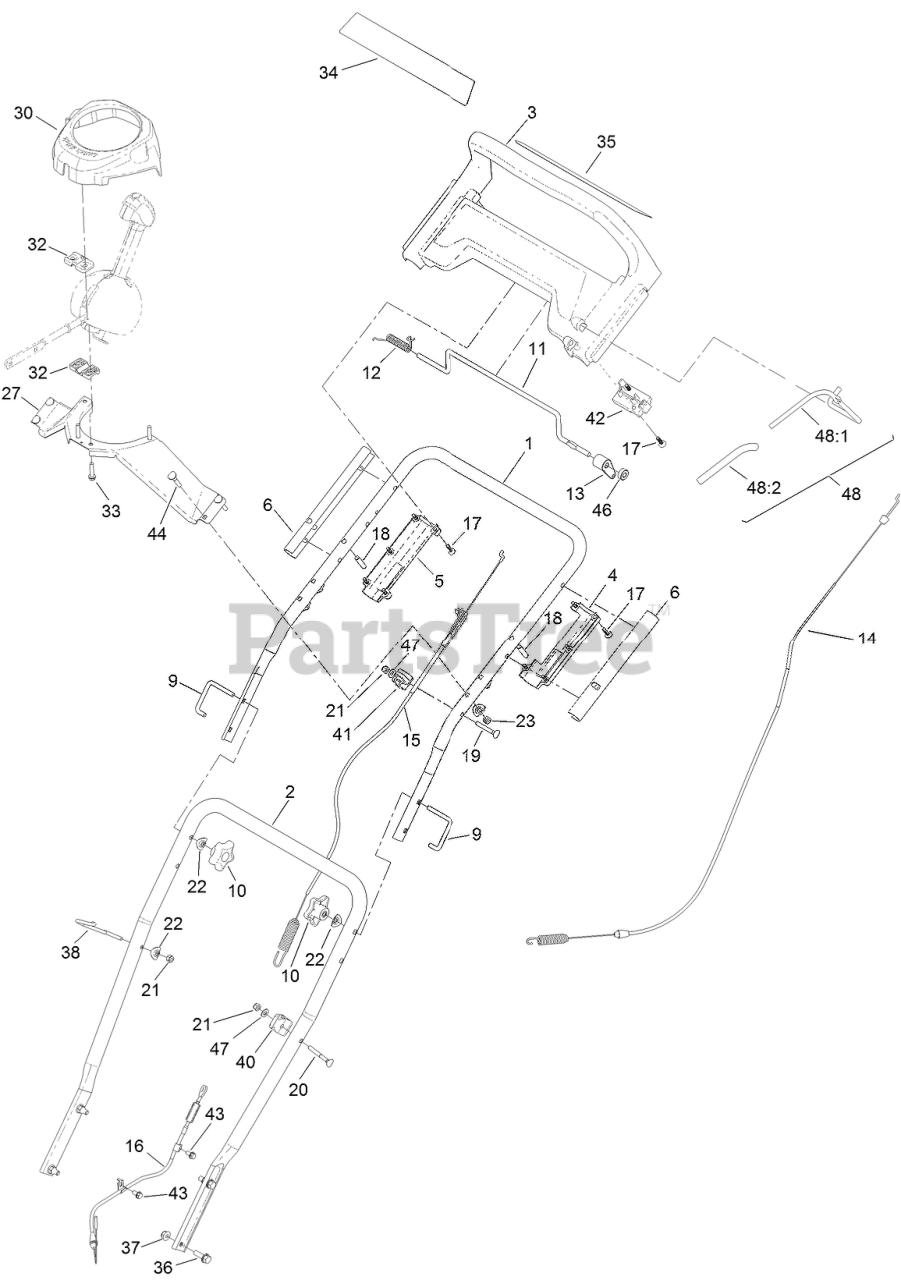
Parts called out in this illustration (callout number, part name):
1	HANDLE-UPPER
2	HANDLE-LOWER
3	HANDLE
4	HANDLE-BOTTOM, LH
5	HANDLE-BOTTOM, RH
6	SLEEVE HANDLE
9	LOCK-HANDLE
10	KNOB-HANDLE
11	BAR-CONTROL, TRACTION
12	Spring-Torsion
13	LEVER-TRACTION
14	CABLE-TRANSMISSION
15	CABLE-ROTOR, UPPER
16	CABLE-ROTOR, LOWER
18	PIN-DOWEL
19	SCREW
20	SCREW-HANDLE
21	NUT-LOCK, NI
22	WASHER
23	NUT-LOCK, NI
27	BRACKET-CHUTE, CONTROL
30	COVER TOP
32	SUPPORT-ROD
33	SCREW-PLASTITE
34	DECAL-DISPLAY
35	DECAL-CONTROL, PANEL
36	SCREW-HHF
37	NUT-HF, NI
38	GUIDE-ROPE
40	ANCHOR-CABLE, UPPER
41	CABLE-GUIDE
42	BAIL-MOUNT
43	SCREW-HWH
44	SCREW-HANDLE
46	SPACER
47	WASHER-FLAT
48	BAIL ASM
48:1	BAIL-AUGER
48:2	COVER-BAIL
